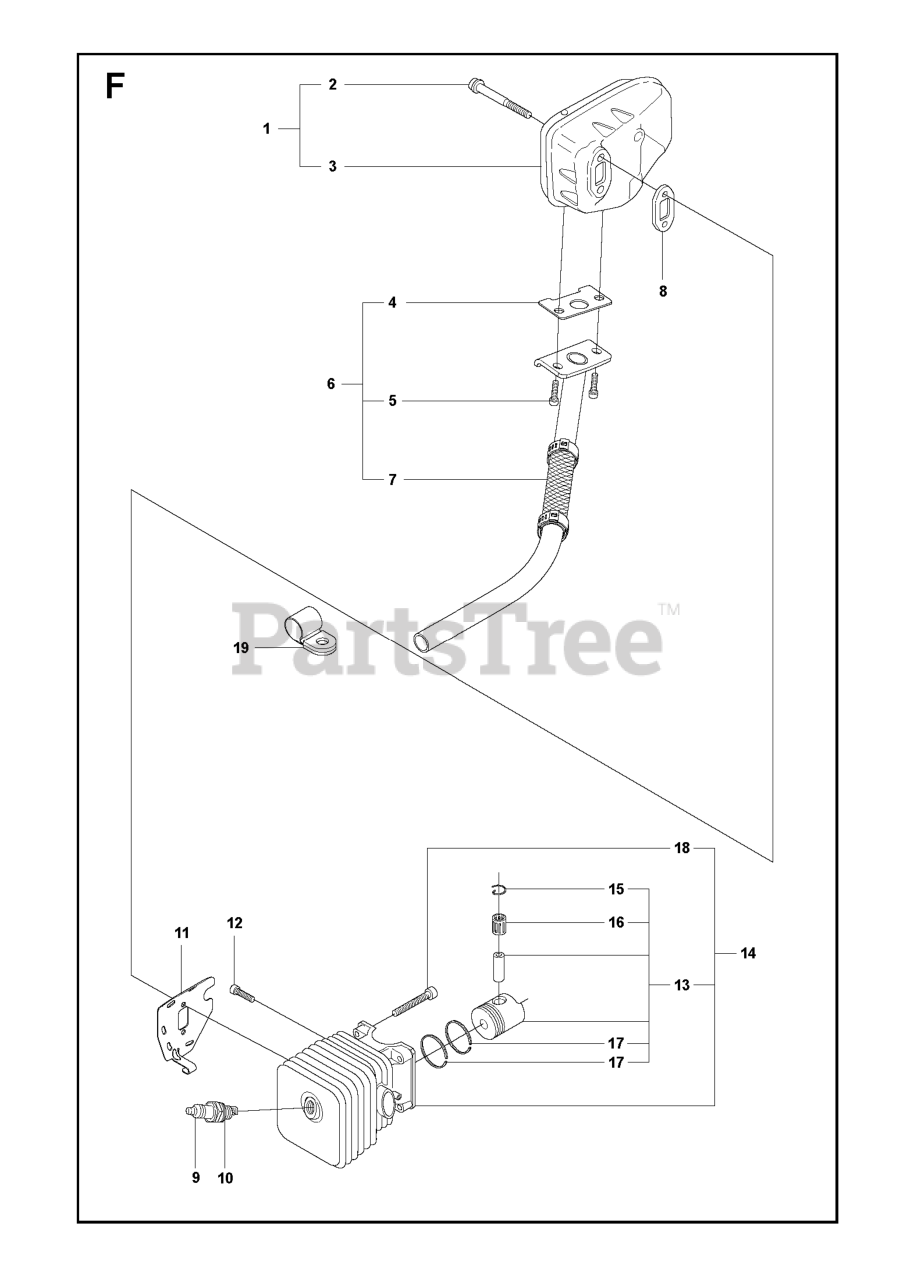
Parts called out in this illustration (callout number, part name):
4	GASKET EXHAUST PIPE
9	SPARK PLUG RCJ7Y
10	SPARK PLUG M14X1.25 NGK BPMR7A
11	AIR CONDUCTOR
12	SCREW M5X14
13	PISTON
17	PISTON RING
18	SCREW MC6S 5X35
